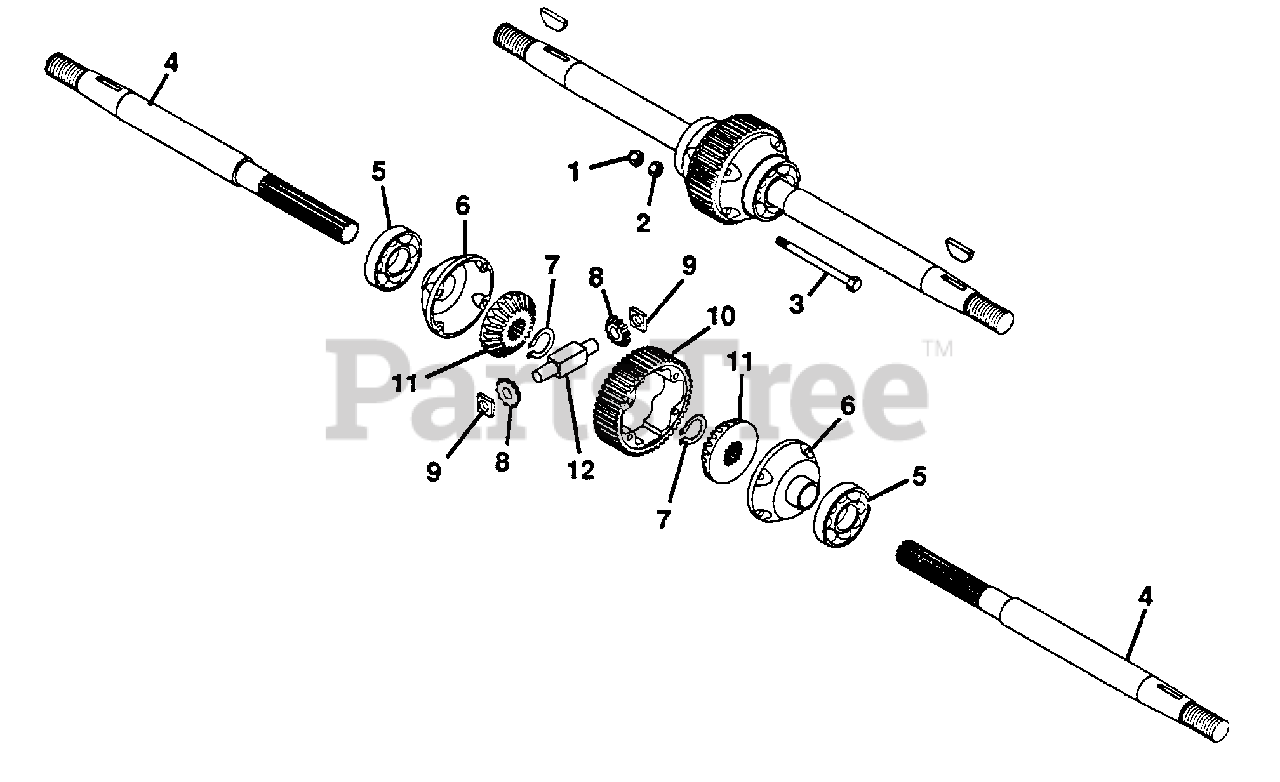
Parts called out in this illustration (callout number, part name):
1	NUT, LOCK 5/16-18
2	NUT, HEX 5/16-18 GRADE-8
3	BOLT, HEX 5/16-18X2.75 GRADE-8
4	AXLE, BEVEL GEAR DIFFERENTIAL
5	BEARING, BALL 1.378X2.834X.699
6	CAP, DIFFERENTIAL END
7	RING, RETAINING 1.000 SHAFT
8	PINION, BEVEL
9	BLOCK, DRIVE
10	GEAR, FINAL DRIVE
11	GEAR, BEVEL
12	PIN, SPIDER PINION
